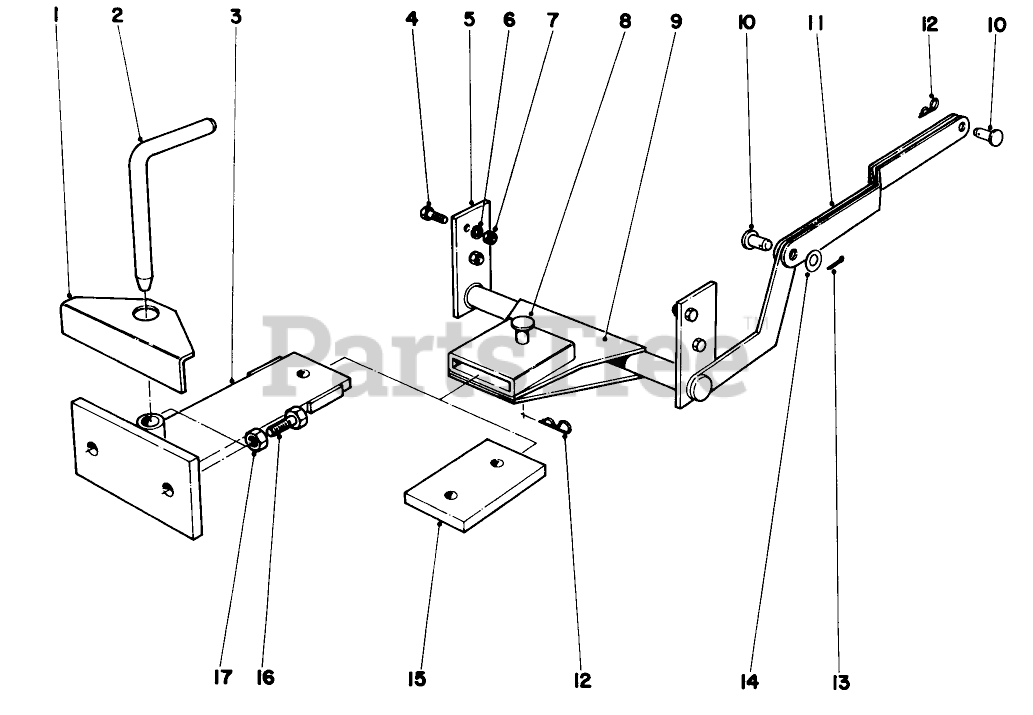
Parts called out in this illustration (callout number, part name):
1	Plate
3	Hitch Adjustment Assembly
4	SCREW-HH
5	Plate
6	WASHER-LOCK
7	NUT-HEX
8	Pin
9	Hitch Assembly
10	Pin
11	Strap
12	PIN-COTTER, HAIR
13	PIN-COTTER
14	Washer
15	Adapter
16	Bolt, Special
17	NUT-JAM
